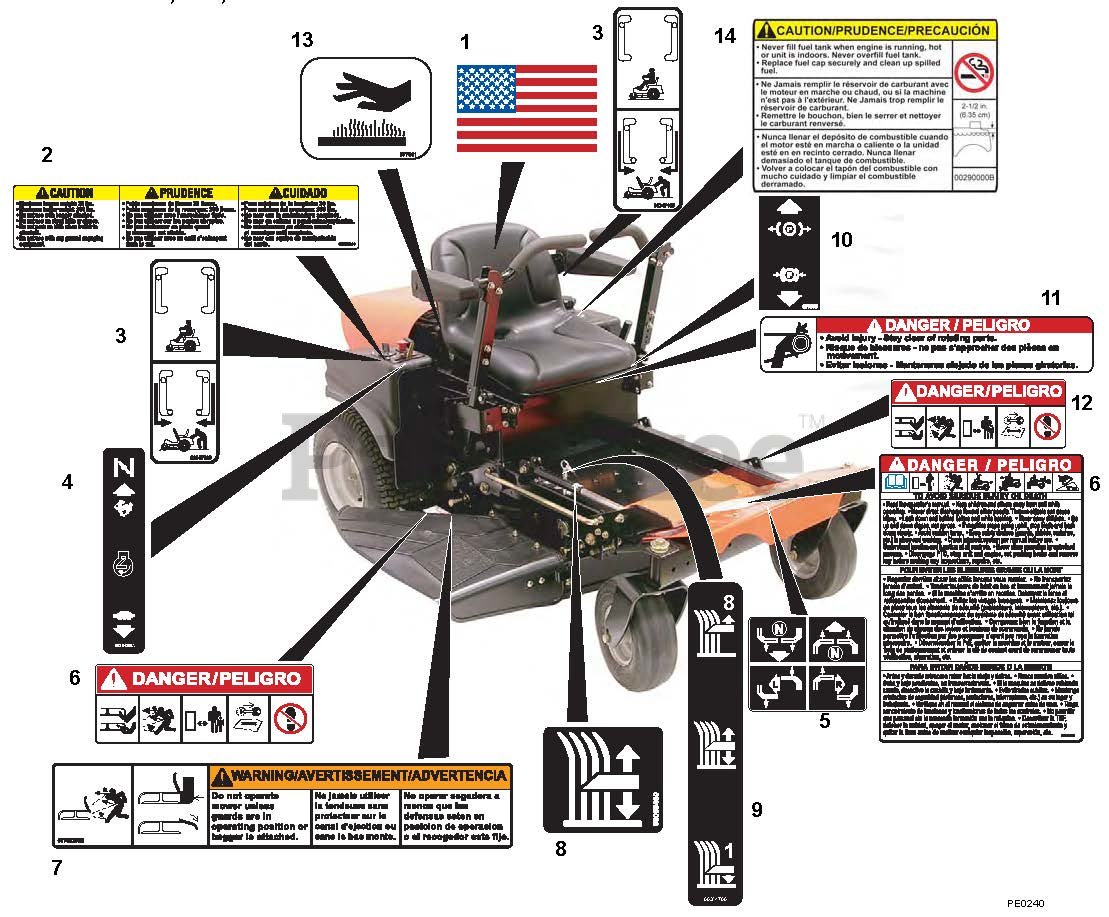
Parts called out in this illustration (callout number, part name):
1	Decal, American Flag
2	Decal, Trailer Hitch
3	Decal, Transmission Disconnect
4	Decal, Control
5	Decal, Instructional Steering
6	Decal, Mower Pan Head Danger
7	Decal, Warning
8	Decal, Cut Height
9	Decal, Cut Height
10	Decal, Bilingual Danger
11	Decal, Parking Brake Lever
12	Decal, Danger
13	Decal, Hot Surface
14	Decal, Fuel Warning
